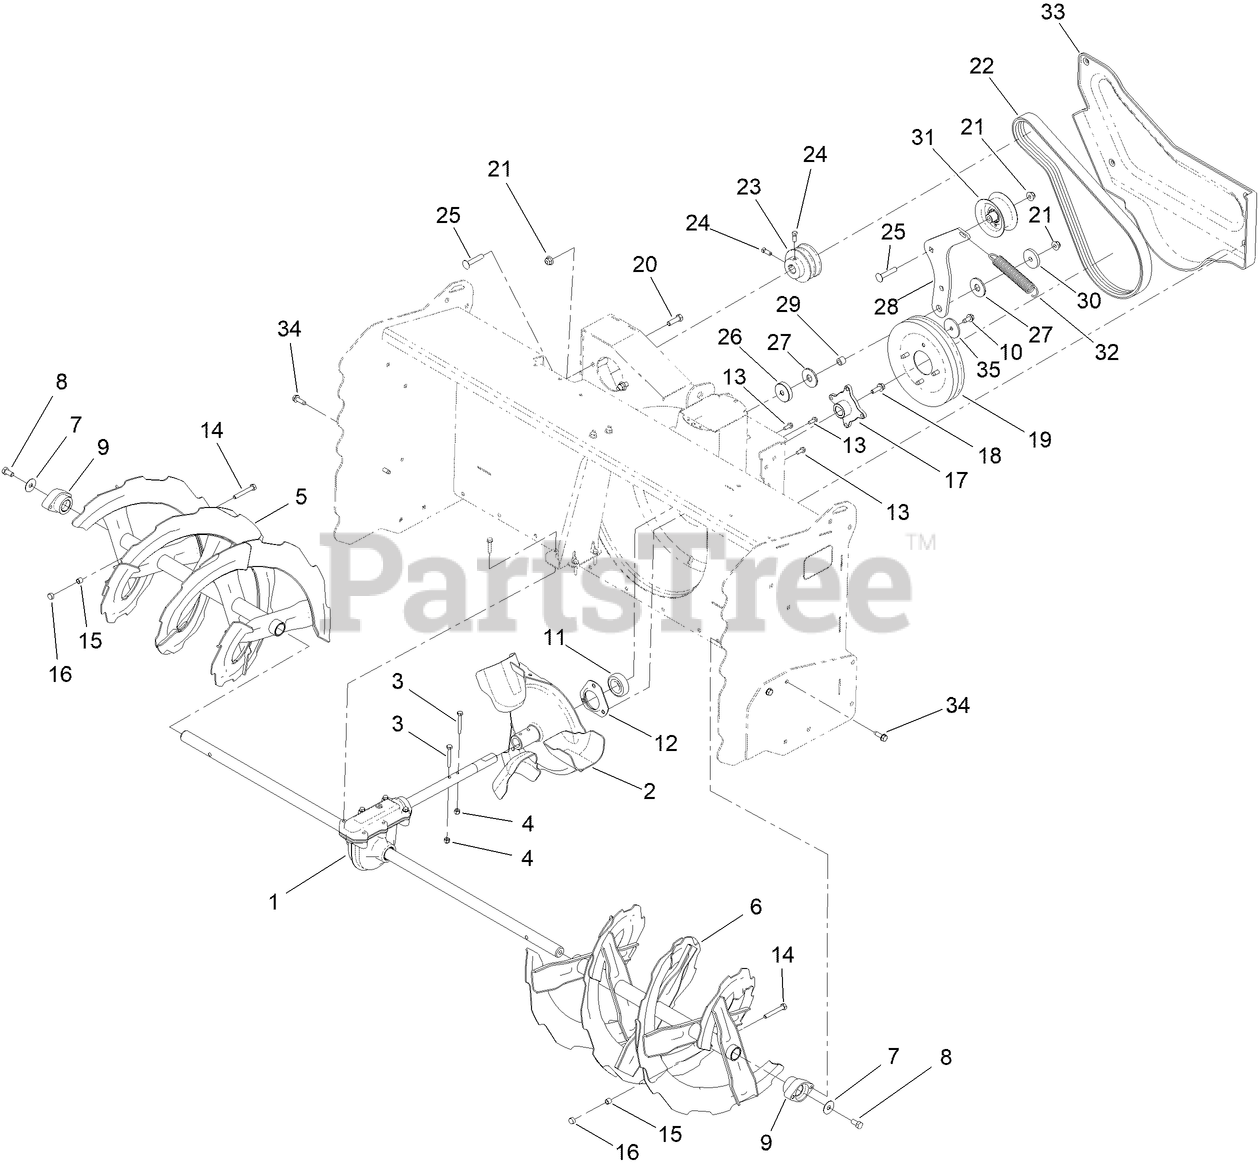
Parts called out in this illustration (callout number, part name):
1	AUGER GEARCASE ASM, 48N
2	IMPELLER
3	SCREW-HH
4	NUT-HEX
5	AUGER, GS-48 RH [BLACK]
6	AUGER, GS-48 LH [BLACK]
7	WASHER
8	SCREW-HH
9	BEARING-AUGER
10	SCREW-HWHTF
11	BEARING-BALL
12	RETAINER-BEARING
13	SCREW-HWH
14	SCREW-HH
15	SPACER-GROMMET
16	NUT-HEX
17	HUB-PULLEY
18	SCREW-HHF
19	PULLEY-IMPELLER, DOUBLE SHEAVE
20	SCREW-HH
21	NUT-HF, NI
22	BELT-V
23	PULLEY
24	SCREW-SET
25	BOLT-CARRIAGE
26	WASHER
27	WASHER-FRICTION, COMPOSITE
28	ARM-IDLER
29	BUSHING-LEVER, LIFT
30	WASHER-PLAIN
31	PULLEY, IDLER
32	SPRING
33	COVER-BELT
34	SCREW-THD ROLL, HWH
35	WASHER-PLAIN
